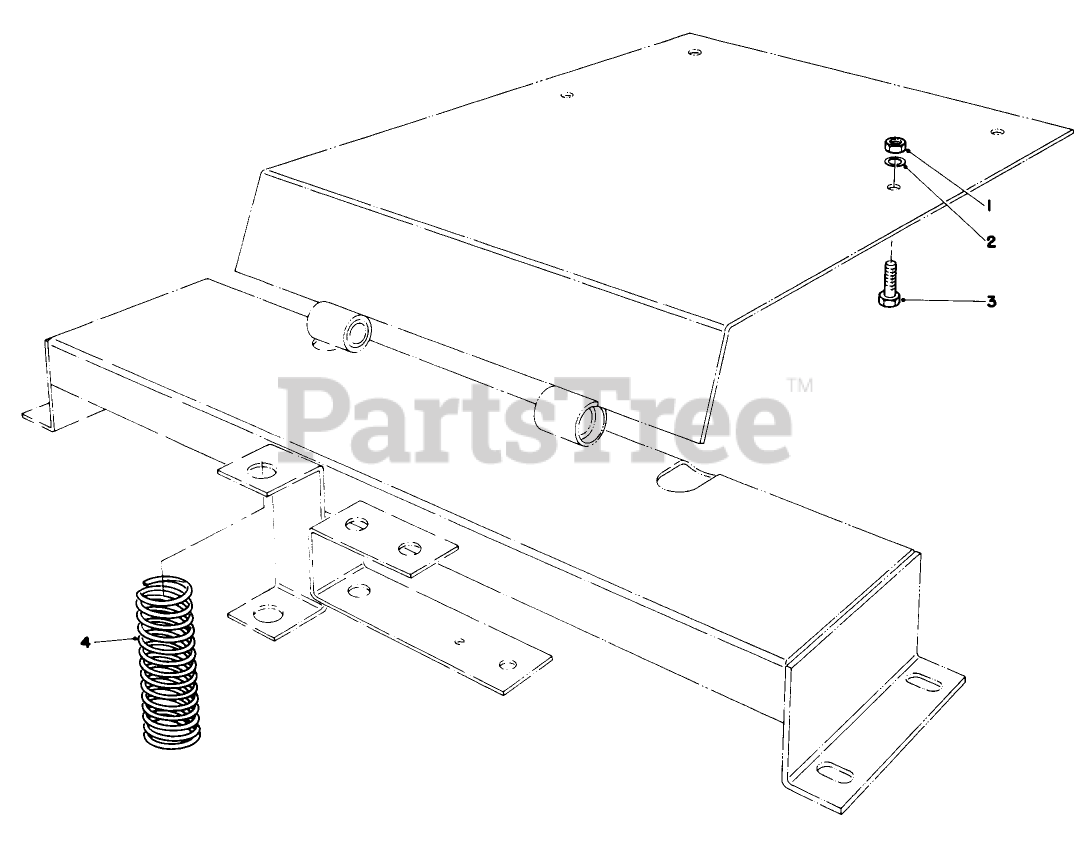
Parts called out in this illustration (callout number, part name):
1	NUT-HEX
2	WASHER-LOCK/SP
3	SCREW-HH
4	COMP SPRING
